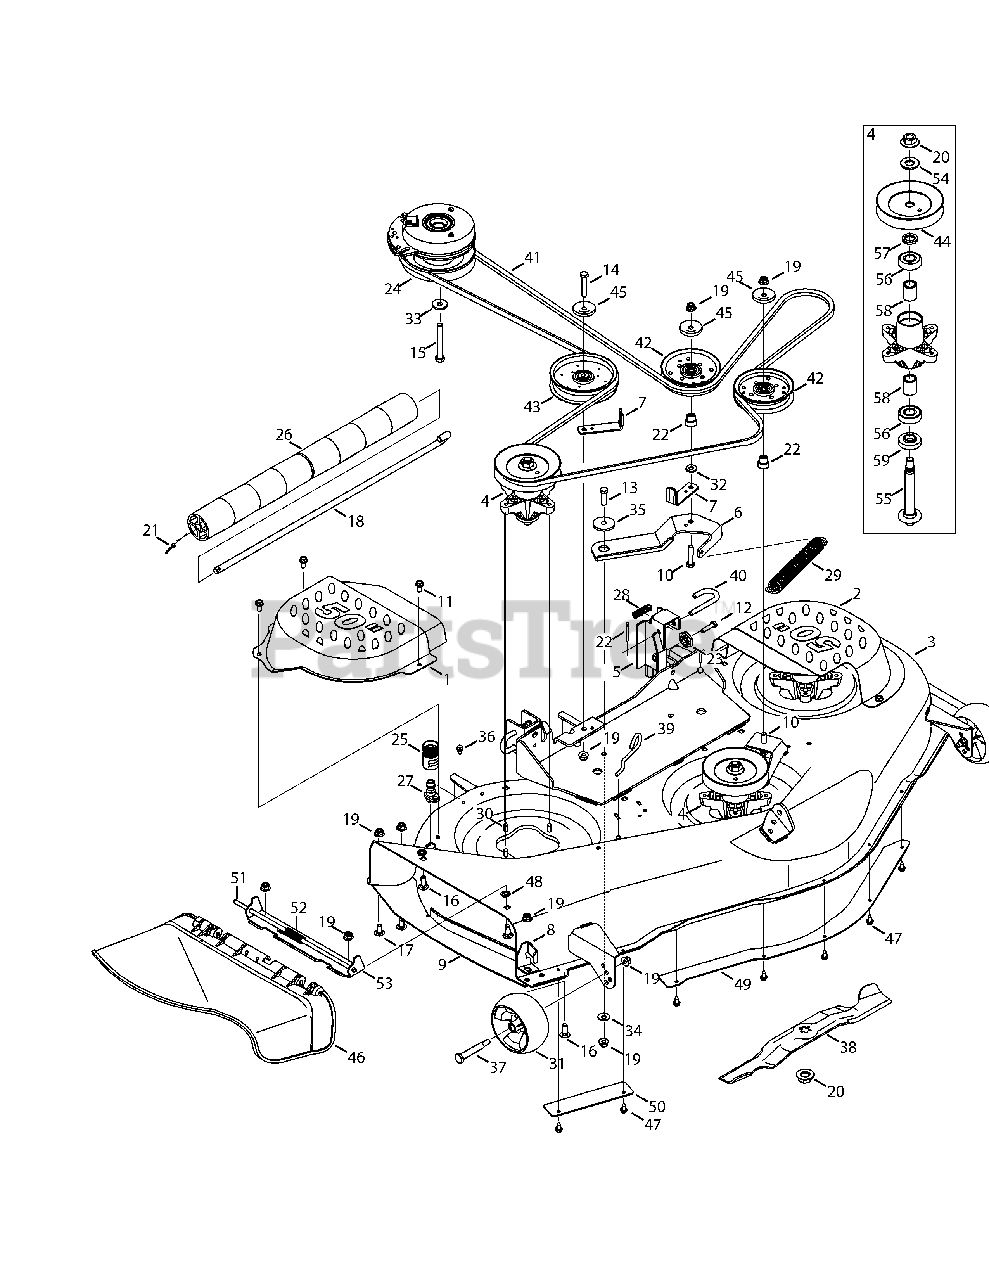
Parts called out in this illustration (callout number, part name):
1	Belt Cover, RH
2	Belt Cover, LH
4	Spindle Assembly
5	Deck Lift Bracket
6	Idler Arm
7	Bracket Belt Guard
10	Hex Cap Screw, 3/8-16 x 1.75
11	Hex Washer Screw, 5/16-18 x .750
12	Hex Cap Screw, 5/16-18 x 1.25
13	Hex Cap Screw, 3/8-16 x 1.25
14	Hex Cap Screw, 3/8-16 x 2.00
15	Screw, 7/16-20 x 3.25
16	Carriage Screw, 3/8-16 x 1.00
17	Carriage Screw, 3/8-16 x .75
19	Flange Lock Nut, 3/8-16
20	Hex Flange Nut, 5/16-18
21	Cotter Pin, 5.32 x 1.25
22	Shoulder Spacer
23	Deck Adjustment Gear
24	Electric PTO Clutch
25	Water Nozzle Adapter
26	Front Roller
27	Deck Wash Nozzle
28	Compression Spring, .66 x 1.9
29	Extension Spring, 1.25 OD x 1.751
30	Hex Washer Screw, 5/16-18 x .750
31	Deck Ball Wheel, 5.0
32	Flat Washer, .385 x .870 x .092
33	Flat Washer, .450 x 1.25 x .164
34	Bell Washer, .45 x 1.0 x .062
35	Shoulder Spacer, .884 x .190
36	Shoulder Screw, .500 x 1/4-20
37	Shoulder Screw, .5 x 2.5 x 3/8-16
38	Blade, 2 in 1, 17.9
39	Deck Spring Rod
40	Deck Hanger Rod
42	Idler Pulley, 4.25 Dia
43	Idler Pulley, 5.00 Dia.
44	V-Type Pulley, 5.39
45	Pulley Cap
46	Discharge Chute Assembly
47	Hex Washer Screw, 1/4-20 x .625
48	Push Nut, 3/8
52	Torsion Spring
53	Chute Bracket
54	Flat Washer, .76 x 1.50 x .12
55	Spindle Shaft, 5.75
56	Ball Bearing
57	Spacer, .79 x 1.25 x .175
58	Spacer, .80 x 1.10 x 1.32
59	Spacer, .79 x 1.82 x .55
